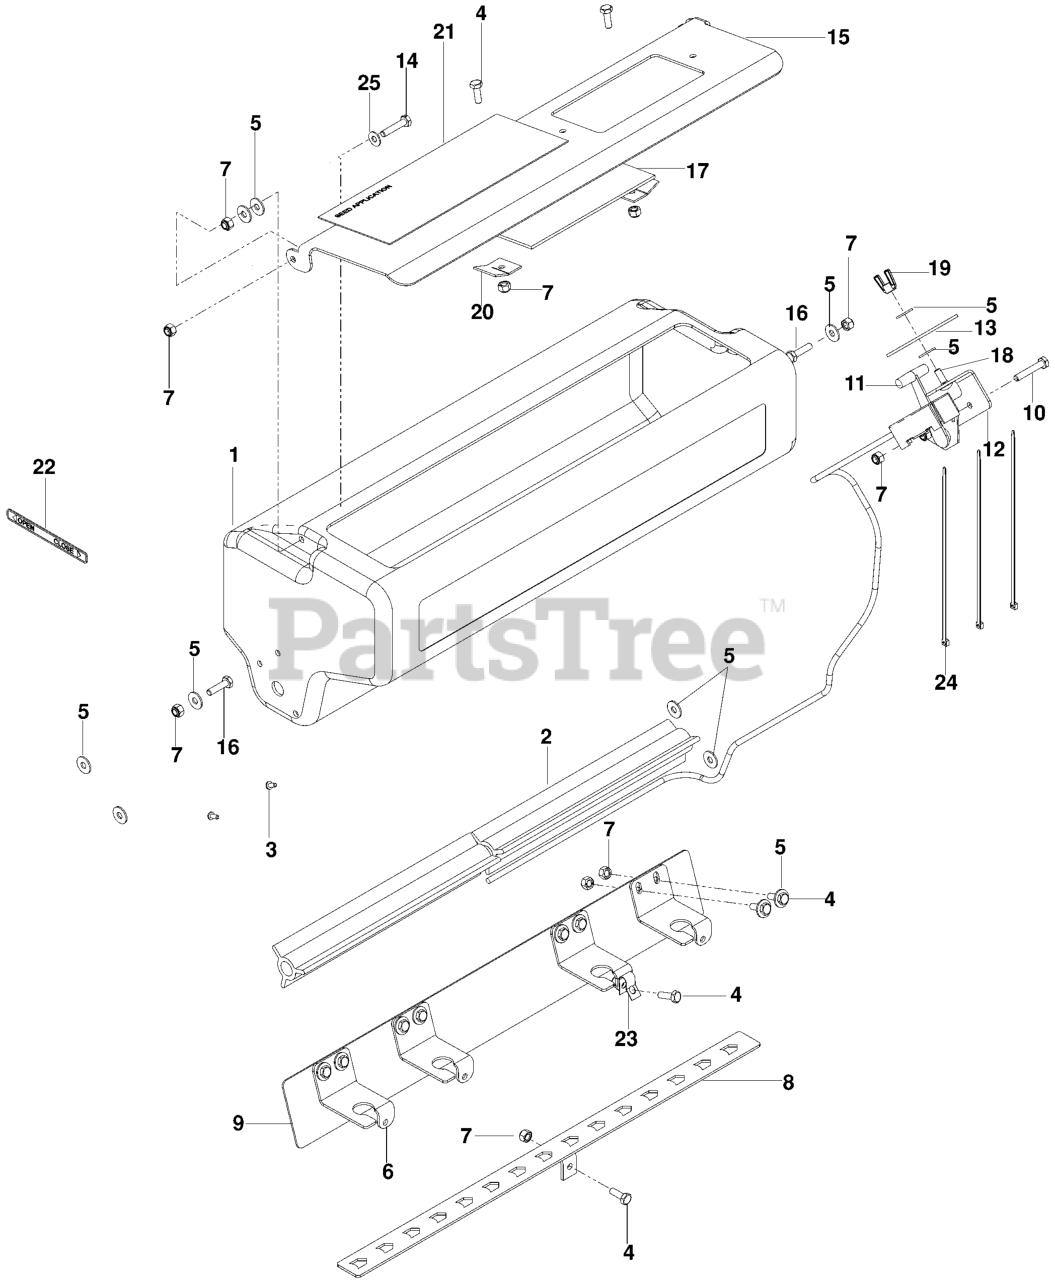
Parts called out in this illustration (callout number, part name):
1	SEED BOX CHARCOAL GREY
3	R/B 108495 SCR SLF TP 8-32X3/8
4	HCS 1/4C X 3/4 HCS
5	WASHER 1/4 FLAT
7	NUT.1/4-20.HEX.NYLOC.ZD
10	SCW 1/4-20 X 1-1/2 HEX
11	CONTROL, PUSH/PULL ASSEMBLY
14	BOLT HEX 1/4 X 1-1/4
15	SEED DOOR ORANGE
16	HCS 1/4 X 1
17	SEED WINDOW
18	RHSNB 1/4C X 3/4
19	WING NUT 1/4
20	WINDOW CLIP
21	DECAL, SEED APPL
22	DECAL, OPEN/CLOSE
23	BRACKET, PUSH/PULL
24	TIE, PLASTIC
25	WASHER 1/4 SAE
